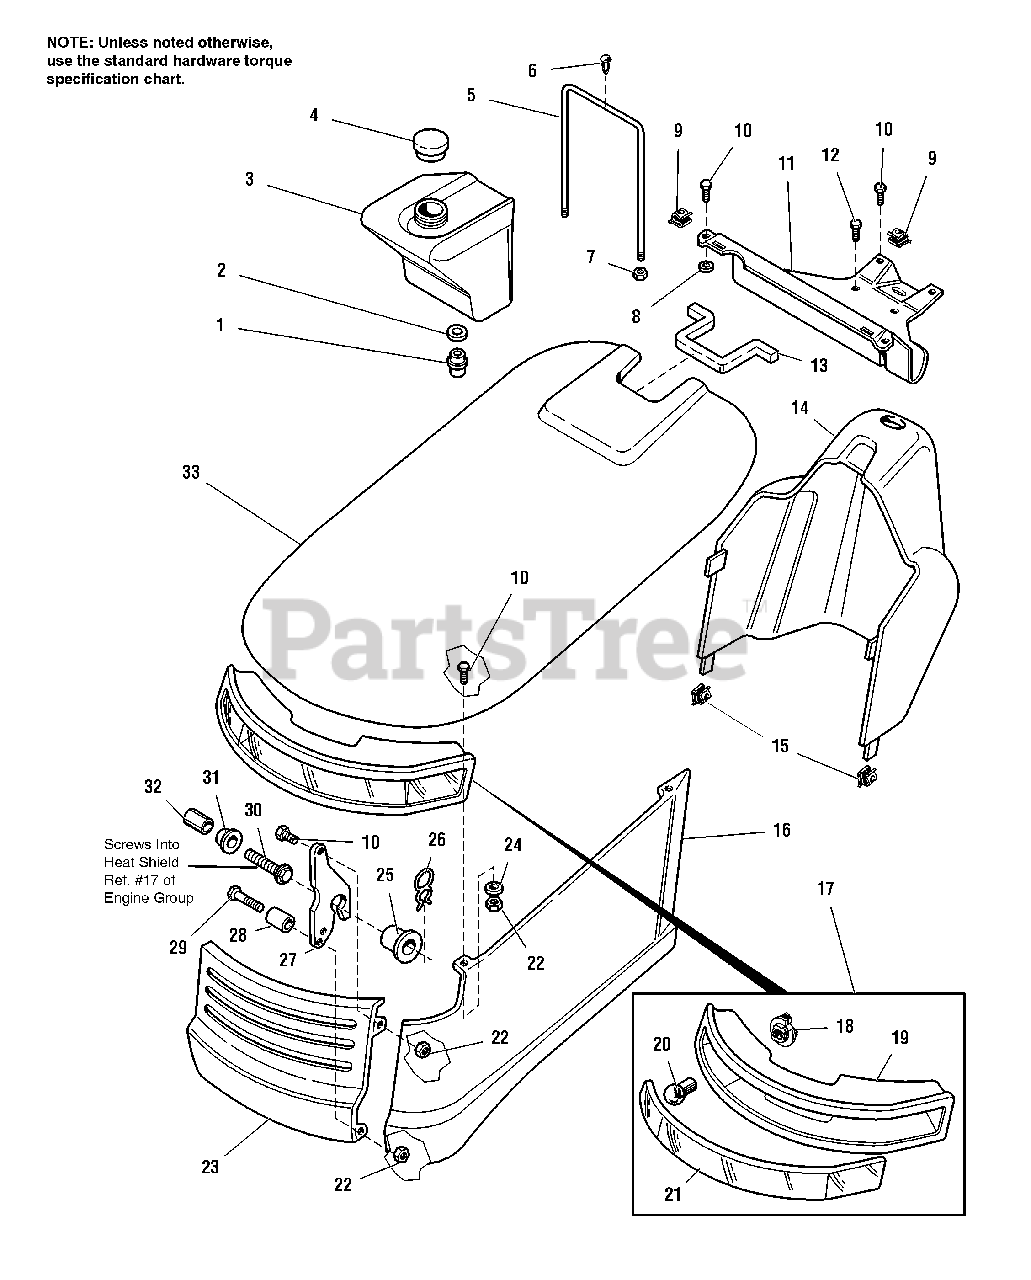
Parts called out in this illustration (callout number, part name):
1	FITTING, Fuel
2	GROMMET, Fuel Fitting
4	CAP, Fuel Tank
6	FASTENER, Plastic, Ratchet
7	NUT, Hex Nylon Lock, 5/16-18
8	WASHER, 1/4
9	PAL NUT, 1/4-20
10	CAPSCREW, Whiz Lock Hex Hd, 1/4-20 x 5/8
12	CAPSCREW, Taptite Hex Washer Hd, 1/4-20 x 1/2
13	GROMMET, Strip
16	PANEL, Side, LH, Orange
16	PANEL, Side, LH, Red
17	LIGHT BAR ASSEMBLY
18	SOCKET, Bulb
20	BULB, #1156
22	NUT, Hex, Nylon Lock, 1/4-20
23	GRILLE, Orange
23	GRILLE, Red
24	WASHER, Plain, 1/4
25	SPACER, Plastic, Hood Pivot
26	CLIP, Pivot Spacer Retaining
27	HINGE, Hood
29	CAPSCREW, Hex Hd, 1/4-20 x 1-1/2
30	CAPSCREW, Whiz Lock Hex Hd, 5/16-18 x 1-1/4
31	SPACER, Steel, Hood Pivot, Grooved
32	SPACER, Steel, Hood Pivot
33	HOOD, Orange
